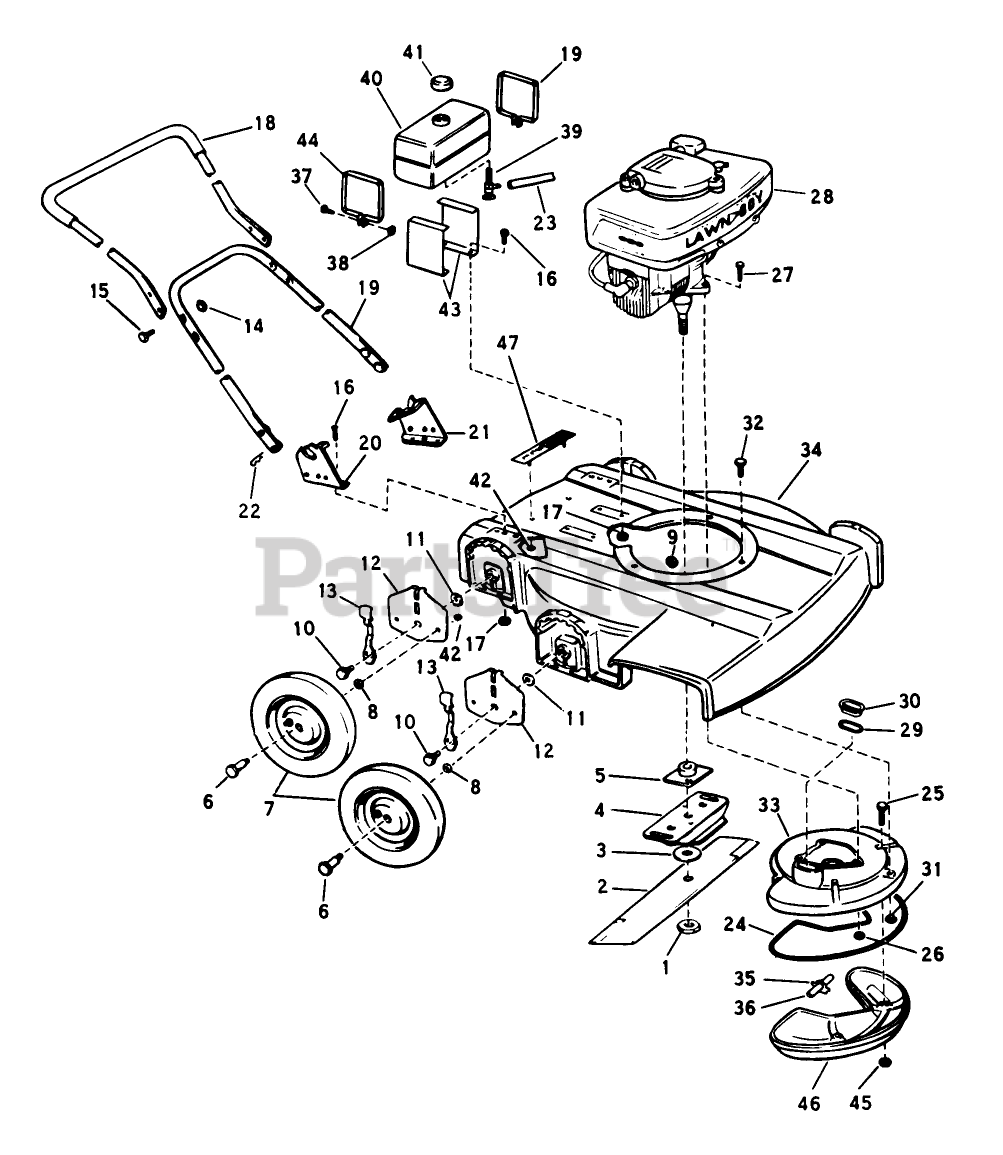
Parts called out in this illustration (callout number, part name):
1	NUT-BLADE
5	PLATE AND COLLAR ASM
6	BOLT-SHOULDER
8	WASHER WROUGHT
12	Lever-Wheel Adj.
14	STOP NUT
16	SCREW S
18	Handle Grip Assy. Top
29	GASKET S
35	Gasket-Internal Tube
36	Tube-Internal Muffler
39	VALVE&SCREEN SM
45	LOCKNUT E
47	Name Plate
